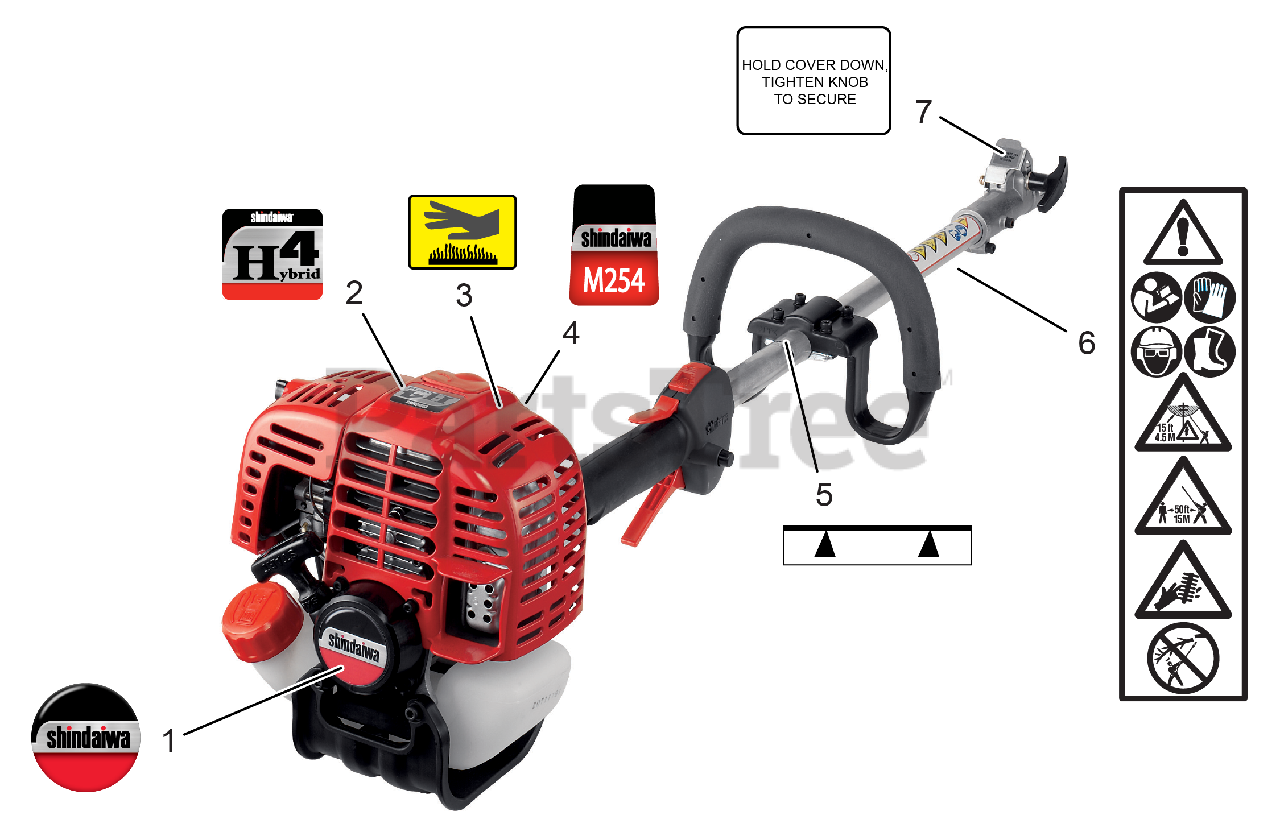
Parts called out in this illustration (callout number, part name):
1	LABEL, RECOIL STARTER
2	LABEL, SHINDAIWA H4
3	LABEL, CAUTION - HOT
4	LABEL, M254
5	LABEL - ALIGNMENT
6	LABEL, CAUTION
7	LABEL, LATCH INSTRUCTION
